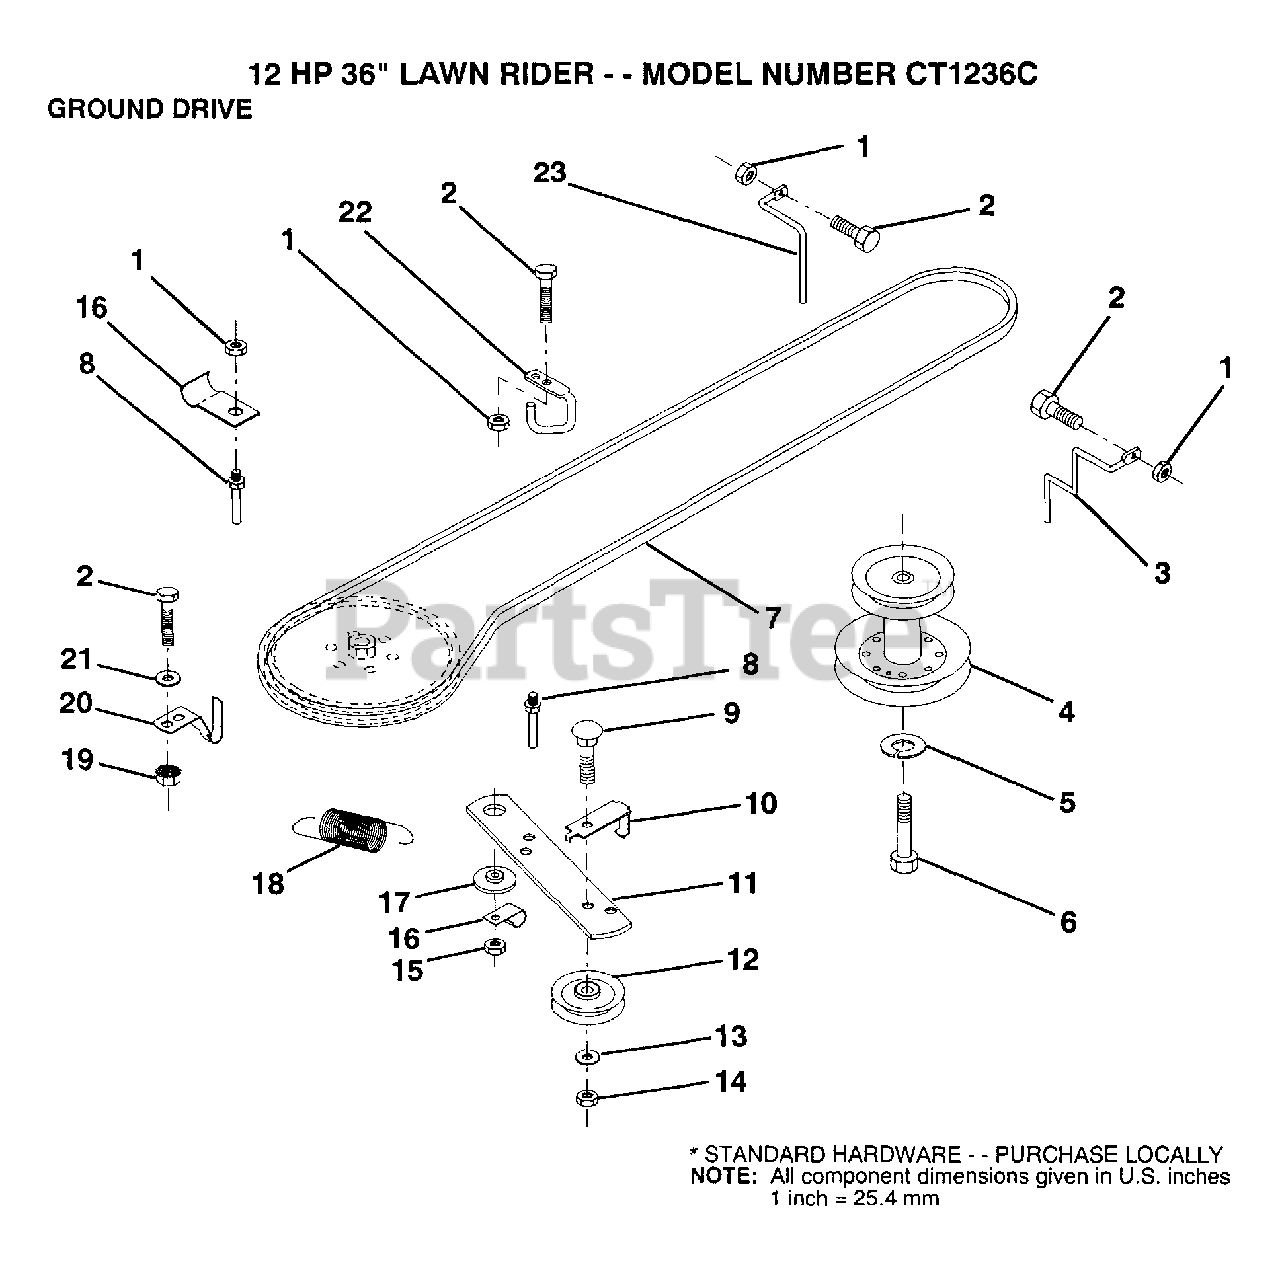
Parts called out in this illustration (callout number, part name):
2	BOLT
5	LOCKWASHER
6	BOLT
7	BELT
8	"KEEPER,DRIVE BELT"
9	BOLT
10	"KEEP,IDLER DR BEL"
13	WASHER
14	LOCKNUT
16	"CLIP,INSULATOR"
17	SPACER RETAINER
20	"KEEPER,DR BELT "
21	WASHER
22	"KEEPER,FRA DR BEL"
